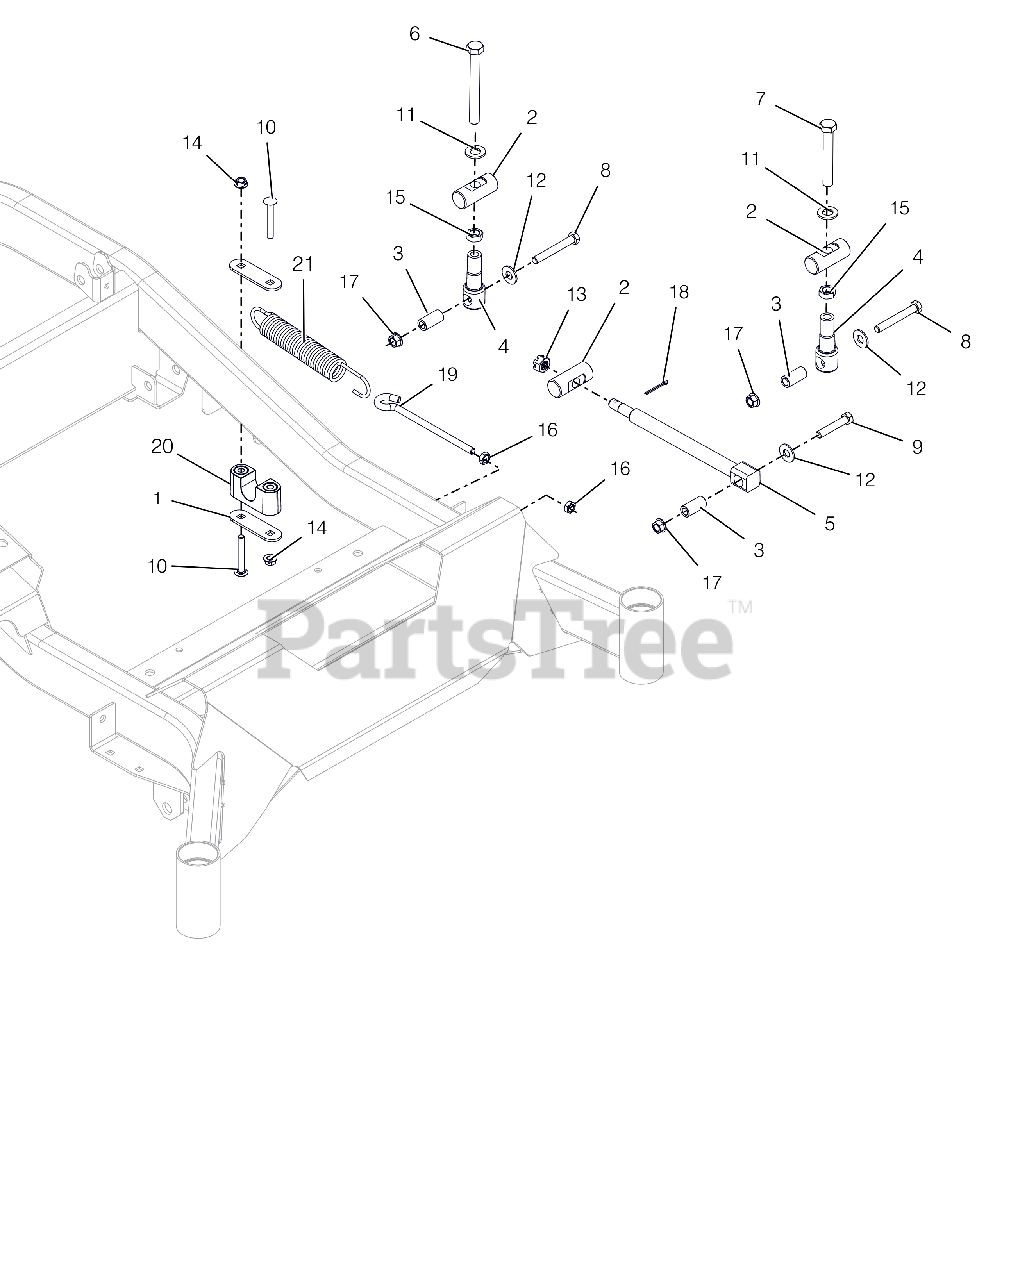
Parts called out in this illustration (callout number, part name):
1	PLATE, BEARING SUPPORT
2	PIN, DECK LIFT
3	SPACER, DECK LEVELING
4	LINK, DECK LIFT FORMED
5	DRAG,LINK-HD
6	@BLT-HEX .5-13-4.5GR8 FULL THD
7	BLT-HEX .50-13X3.50 GR5 FTH
8	BLT-HEX .38-16X2.75 GR8 YWZC
9	@BLT-HEX .38-16X2.00 GR5 YWZC
10	BLT-RDHDSQSHNK .31-18X2.25 YWZ
11	FLATWASHER 1/2 SAE HARD 15906
12	@WSHR-FL-STL.438X1.00X.083 YWZ
13	NUT-SL .50-13
14	@NUT-LK-CTR-FLG .31-18 YZ GR F
15	NUT-JAM .50-13 YWZC
16	NUT-HEX-JAM .375-16 YWZC
17	@NUT-LK-TOP-FLG .38-16 YWZC
18	@PIN-CTR .12X1.25 EXTPRSQCT YZ
19	BOLT,.38-16 X 5.25-.62 DIA EYE
20	ASM-BUSHING, DECK LIFT
21	SG-TENS .162X1.25X8.25 WLD 25
